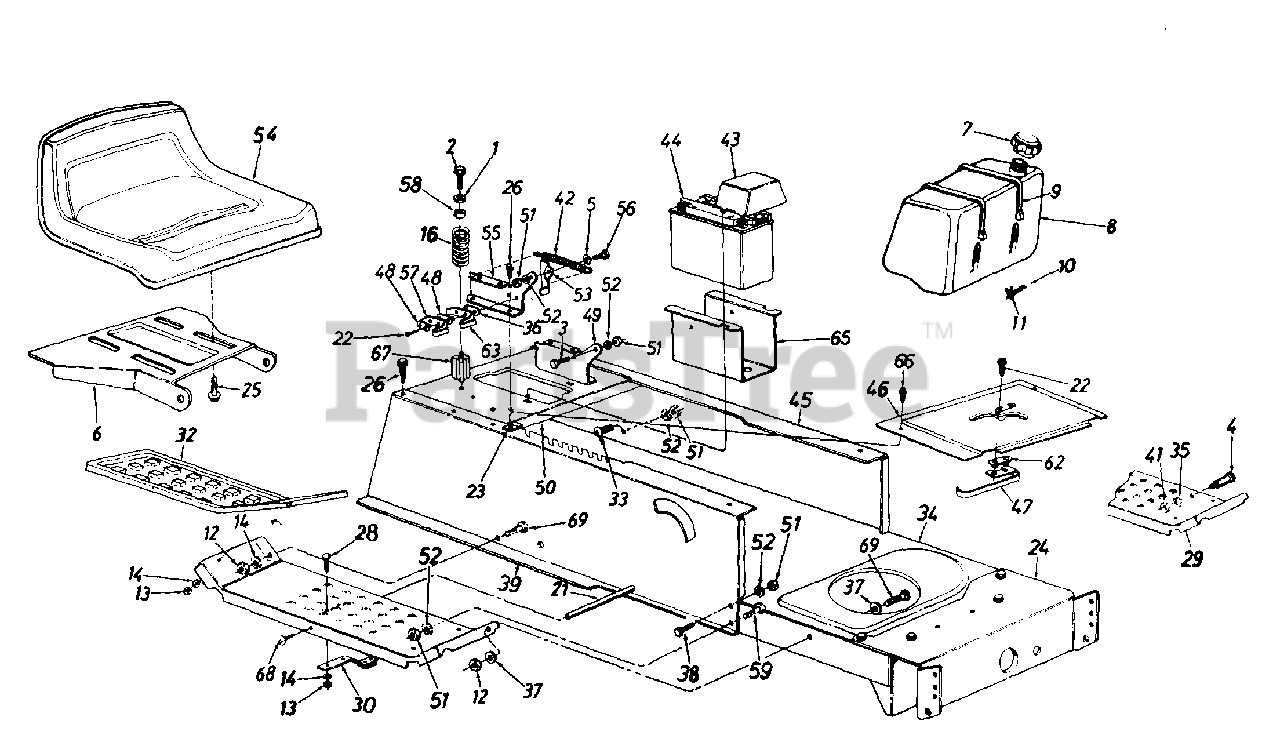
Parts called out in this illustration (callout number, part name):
1	Fl-Wash..344" I.D. x .875"
2	Hex Wash. Hd. Tap Scr. 5/16-18 x 3.25" Lg.
3	Shld. Bolt .437" Dia. x .162"
4	Shld. Bolt .50" Dia. x .84"
5	Spr-Wash..445" I.D. x.75
6	Seat Pivot Bracket
7	Fuel Cap
8	Fuel Tank
9	Tie Strap
10	Fuel Line
11	Hose Clamp
12	Hex Nut 1/4-28 Thd.
13	Hex Nut 1/4-20 Thd.
14	L-Wash. 1/4" I.D.
16	Compression Spring
21	Running Board Rod
22	Hex Wash. Hd. AB-Tap Scr. #8 x .50" Lg,
23	Speed Nut #102
24	Front Pivot Brkt.
25	Hex Tap Scr. 3/8-16 x .75"
26	Hex Wash. Hd. AB-Tap Scr. 5/16 x .75" Lg.
28	Carriage Bolt 1/4-20 x .62"
29	Running Board
30	Blade Brake Ass'y.
32	Rubber Foot Pad - L.H.
33	Truss Mach. Scr. 5/16-18 x .75" Lg.
34	Lower Frame
35	L-Wash. 3/8" I.D.
36	Insulator Boss Plate
37	Fl-Wash..25" I.D. x .625" O.D.
38	Hex Bolt 5/16-18 x .75" Lg.
39	Upper Frame - R.H.
41	Hex Nut 3/8-16 Thd.
42	Extension Spring 5.31" Lg.
43	Battery Cover
44	12-V Battery (275 Cold Crank Amps)
45	Upper Frame - L.N.
46	Shift Cover
47	Reverse Safety Switch
48	Insulator Plate
52	L-Wash. 5/16" I.D.
53	Seat Lift Brkt.
54	Seat 8-7/8" High
56	Shld. Bolt .437" Dia. x .268"
57	Spring Switch
58	Bushing
59	Hex Wash. TT-Tap Scr. 5/16-18 x 7/8" Lg.
62	Insulator Nut Plate
63	Safety Switch (Seat)
65	Battery Tray
66	Truss Mach. B-Tap Scr. #10 x .5" Lg.
67	Spring Spacer
68	Pan Hd. Cutting Scr. 5/16-18 x.75" Lg.
69	Hex Bolt 1/4-28 x .75" Lg.
